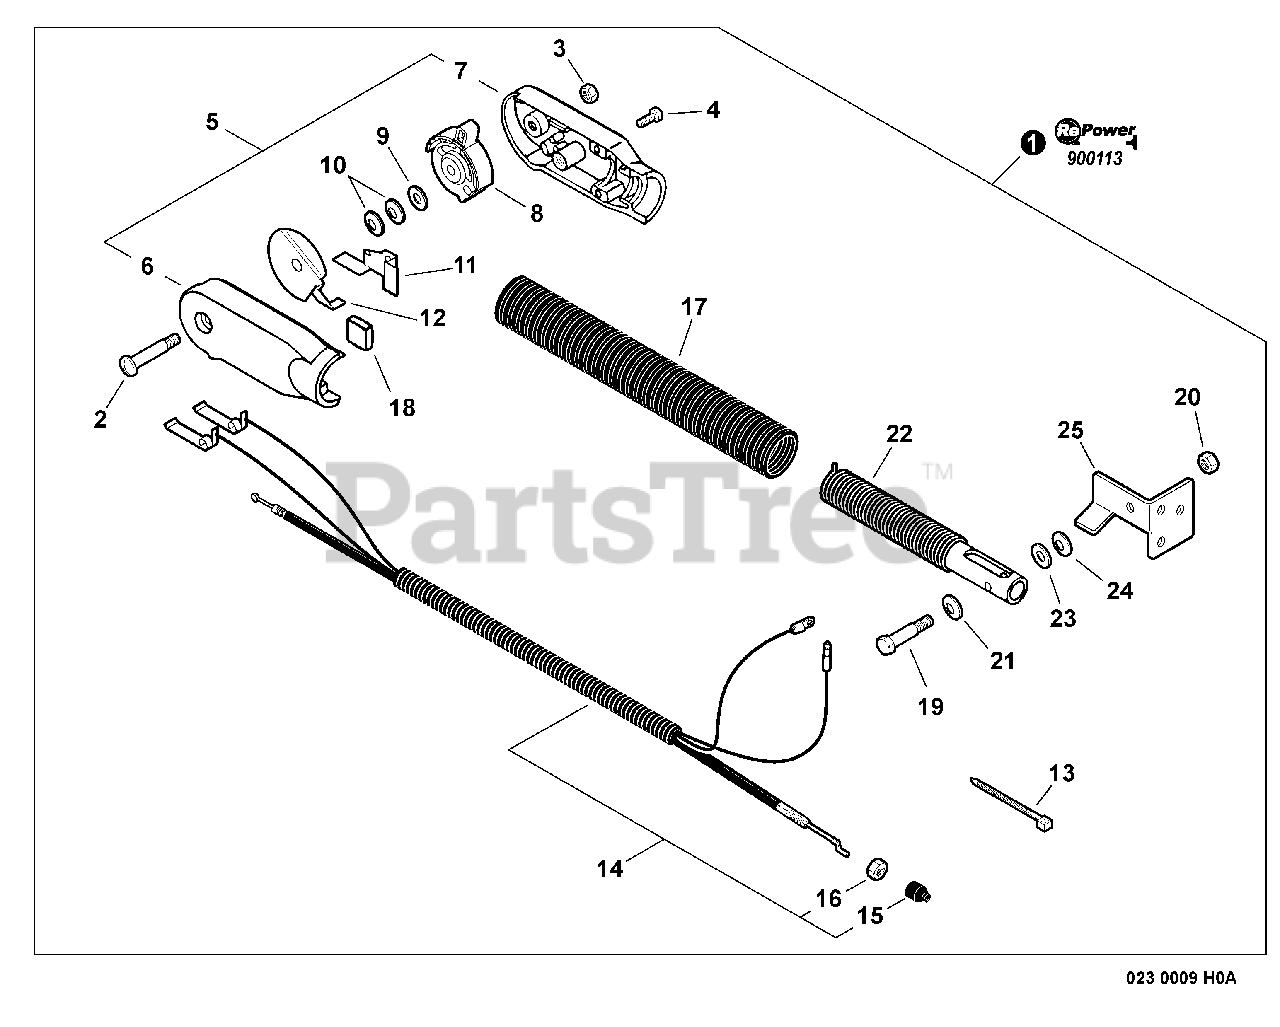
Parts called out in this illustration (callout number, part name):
1	HIP MOUNT THROTTLE CONTROL KIT
2	SCREW - 4
3	LOCKNUT - 4
4	SCREW - 5X20
5	CONTROL HANDLE ASSY
6	HANDLE, CONTROL - LEFT
7	HANDLE, CONTROL - RIGHT
8	LEVER, THROTTLE CONTROL
9	WASHER - 6
10	WASHER - SPRING
11	TERMINAL - GROUND
12	TERMINAL - GROUND
13	TIE, CABLE - SMALL
14	CONTROL CABLE ASSY
15	CAP, DUST
16	LOCKNUT - 6
18	PAD, FOAM
19	BOLT - 6
20	LOCKNUT - 1/4"
21	WASHER - SPRING
22	TUBE, SPRING
23	WASHER - 8
24	WASHER - SPRING
25	BRACKET
